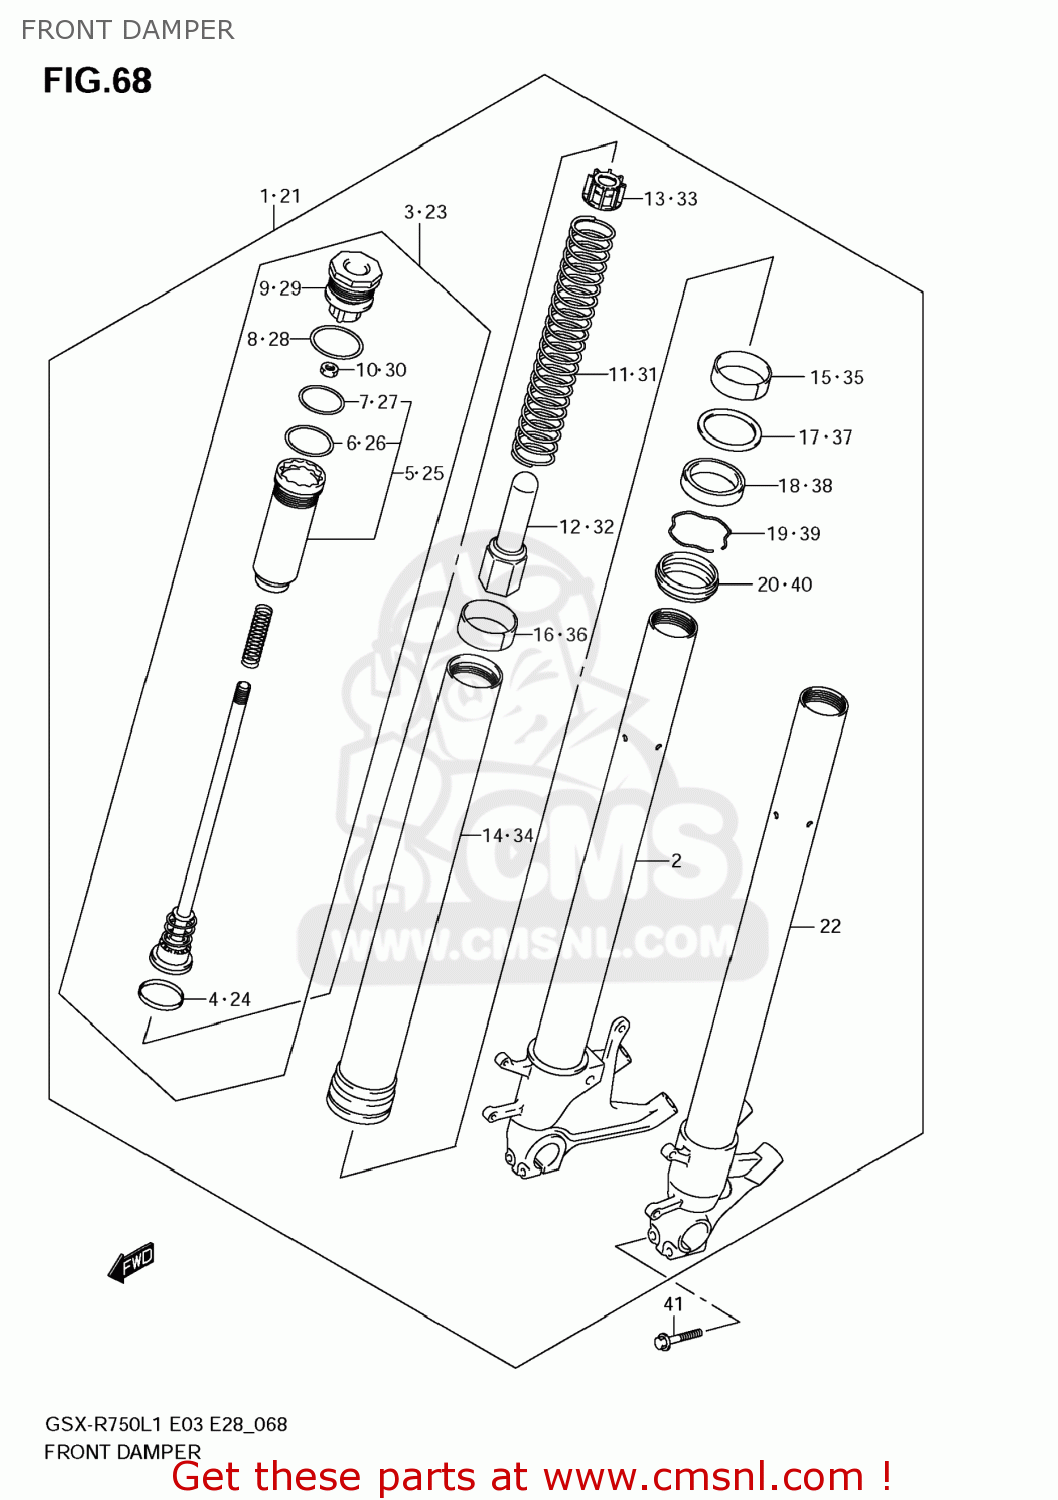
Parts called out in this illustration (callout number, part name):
1	DAMPER ASSY,FR FORK,R
2	TUBE,INNER,R
3	ROD,PISTON
4	RING,PISTON
5	CASE,ROD GUIDE
6	PISTON RING
7	O RING
8	O RING,FORK BOLT
9	BOLT
10	NUT
11	SPRING
12	COLLAR,SPRING
13	COLLAR,SPRING
14	TUBE,OUTER
15	BUSH,GUIDE
16	BUSH,SLIDE
17	SPACER,SEAL
18	SEAL,OIL
19	CIRCLIP,FORK OIL SEAL
20	SEAL,DUST
21	DAMPER ASSY,FR FORK,L
22	TUBE,INNER,L
23	ROD,PISTON
24	RING,PISTON
25	CASE,ROD GUIDE
26	RING,PISTON
27	O RING
28	O RING,FORK BOLT
29	BOLT
30	NUT
31	SPRING
32	COLLAR,SPRING
33	COLLAR,SPRING
34	TUBE,OUTER
35	BUSH,GUIDE
36	BUSH,SLIDE
37	SPACER,SEAL
38	SEAL,OIL
39	CIRCLIP,FORK OIL SEAL
40	SEAL,DUST
41	BOLT
